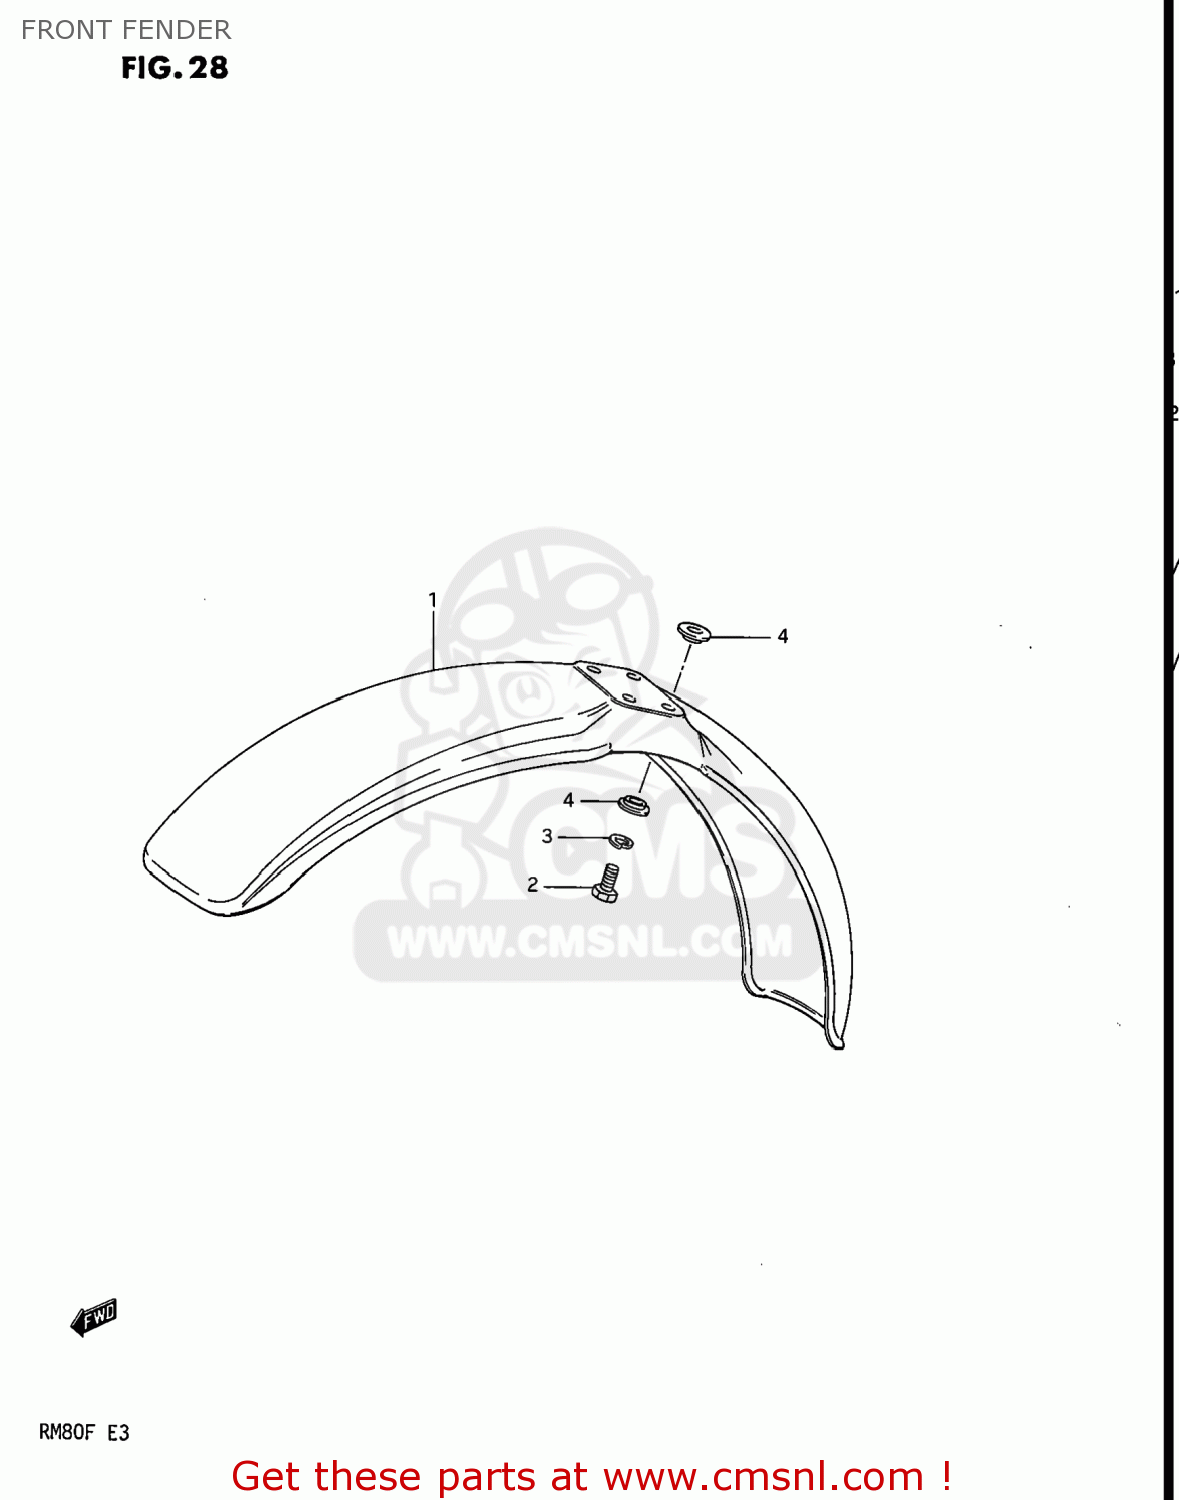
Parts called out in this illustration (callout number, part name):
1	FENDER,FRONT
2	BOLT, UPPER
3	LOCK WASHER
4	SPACER
